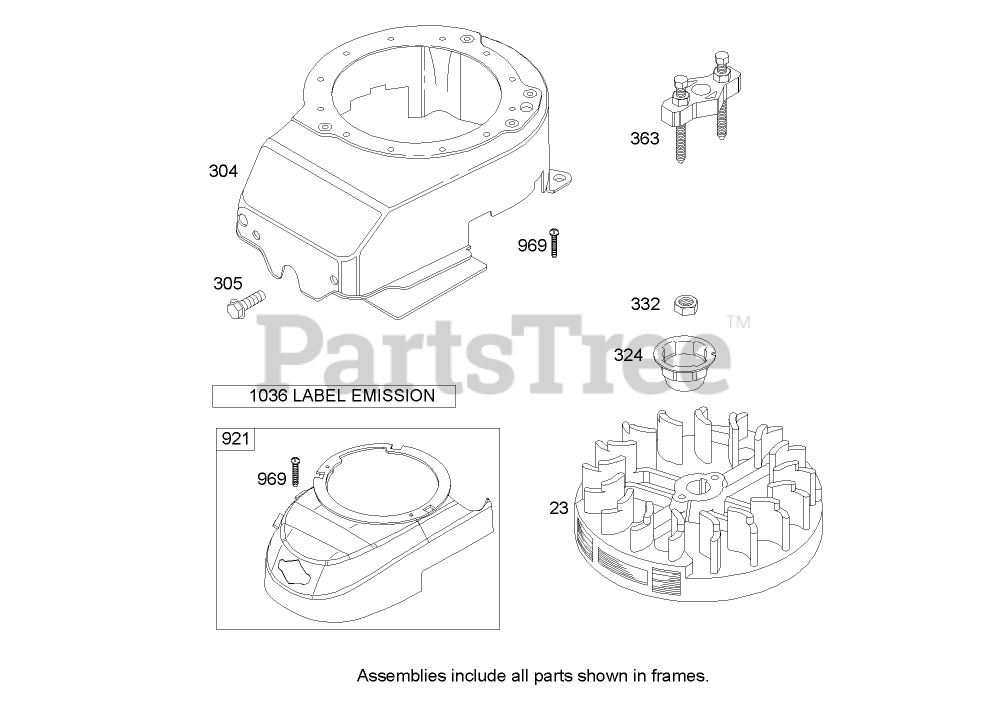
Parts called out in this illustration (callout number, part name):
23	Flywheel
304	Housing-Blower
305	Screw
324	Cup/Screen ASM
332	Nut
363	Puller-Flywheel
921	Cover-Housing, Blower
969	Screw
1036	Label-Emission
